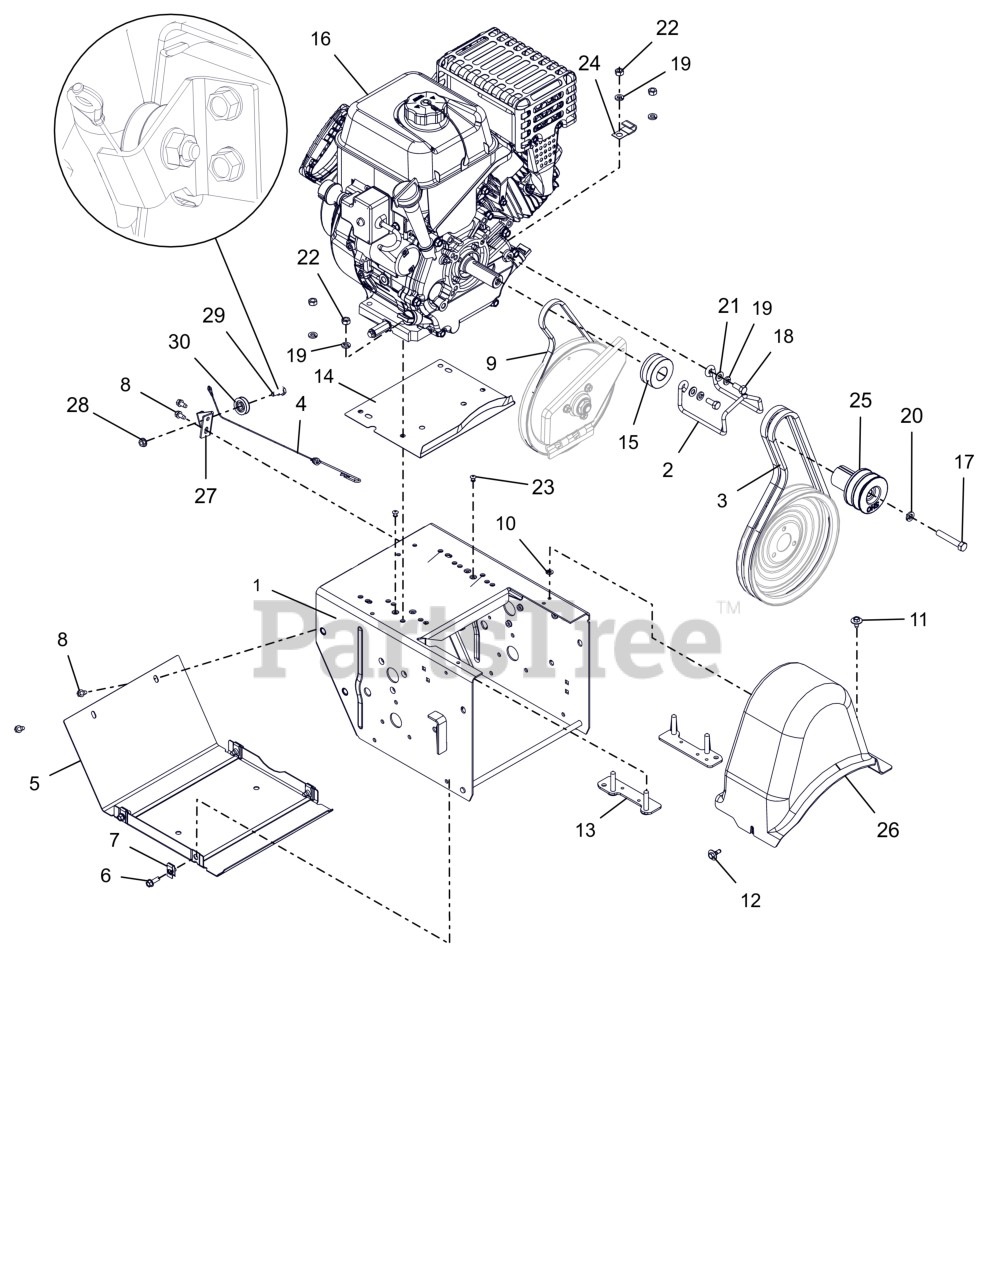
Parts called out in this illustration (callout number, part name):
1	FRAME, MAIN-DELUXE(WELDMENT)
2	FINGER, BELT
3	V-BELT, HA-RAW EDGE (SET)
4	CABLE, LOWER TRACTION,SS & PRO
5	COVER, BOTTOM
6	BLT, HWH .25-20X.75 G5 ZCC
7	NUT-RTNR .25-20X.56
8	SCR-TAP .25-20X.50 HWH ZCC
9	V-BELT, 3L-WRAPPED
10	NUT-PUSH .25X.50 O.D.
11	SCR, TAP .25-20X.50 LG HWH ZCC
12	SCR-TAP .25-20X.5 CAPTIVE
13	STRAP, ENGINE-MEDIUM BLOCK
14	BAFFLE, WATER - LARGE BLOCK
15	SHEAVE, TRACTION (KEYLESS)
16	ENGINE, ARIENS AX291 240V/60W
17	BLT, HEX .38-24X2.25 G5 ZCC
18	BLT, HEX .31-24X.750 G5 ZCC
19	WSHR, LK-HVY .312X.097 ZCC
20	WSHR,LK-REG .375X.094 ZCC
21	WSHR,FLT .344X.688X.065 ZCC
22	NUT, HEX .312-18 ZCC
23	RVT, POP .1875 ZCC
24	J-CLAMP
25	SHEAVE,ATTACHMENT-SHO 2 GRV
26	COVER, BELT-LARGE
27	BRACKET, CABLE PULLEY
28	NUT-LK-TOP-FLG .250-20 GF ZCC
29	BOLT, SHLDR -.375 X .375 X .25-20
30	PULLEY, CABLE
